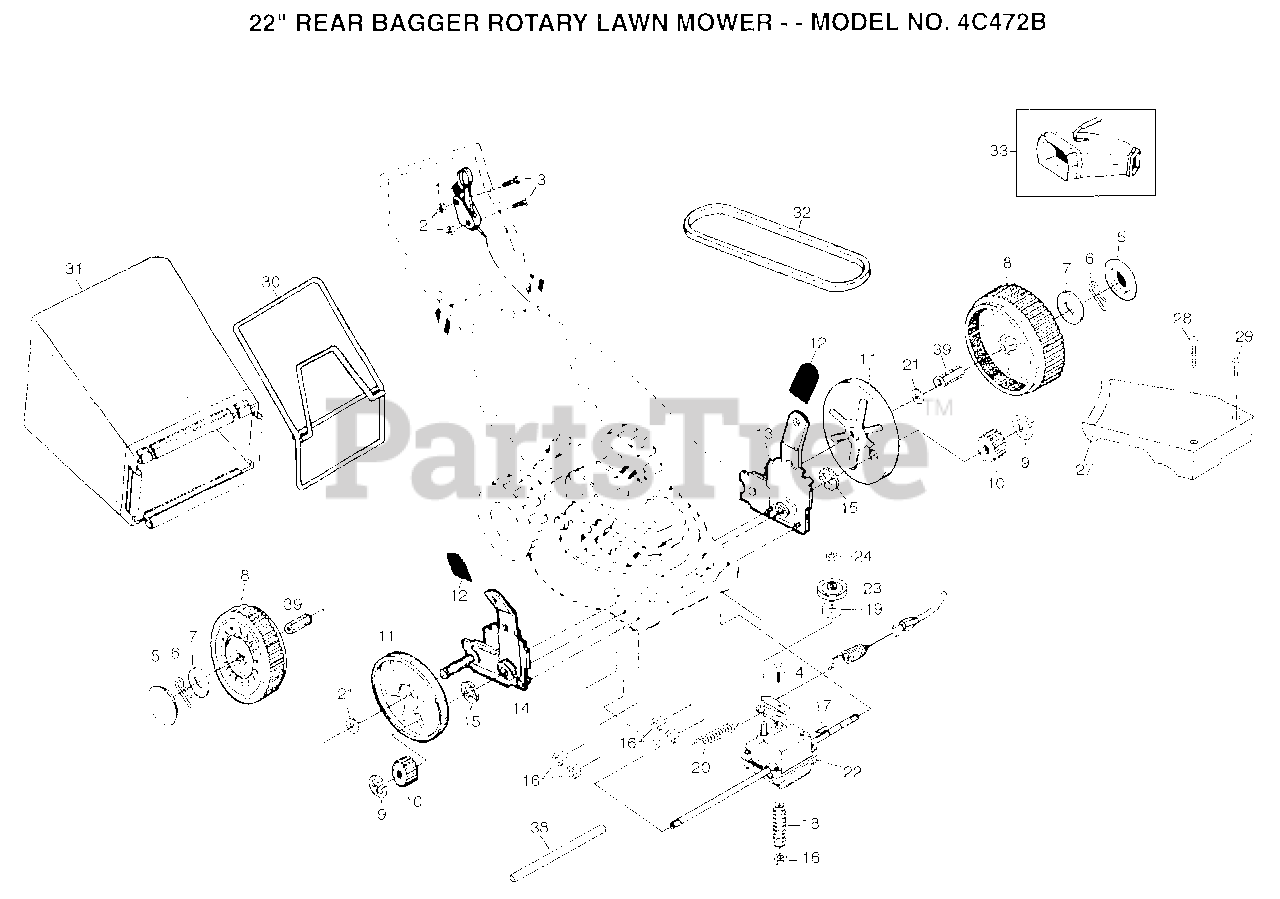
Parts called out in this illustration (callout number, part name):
1	CONTROL.DRIVE
3	SCREW
4	BOLT.1/4-20X2.0
5	HUB CAP
6	RETAINER CLIP PM
7	WASHER
8	WHEEL.8X2.LP.PR
10	PINION.GEAR
11	DUST SHROUD PM
12	KNOB PM
15	WASHER PM
17	HI PRO KEY
18	SPRING.TENSION
19	BEARING
20	SPRING
21	WASHER FLUT
23	PULLEY.DRIVEN
24	LOCKNUT
27	"COVER.DRIVE 22""RD"
30	CATCHER FRAME
31	GRASS BAG
38	DRV SHAFT TUBE PM
39	BUSHING.HEX
